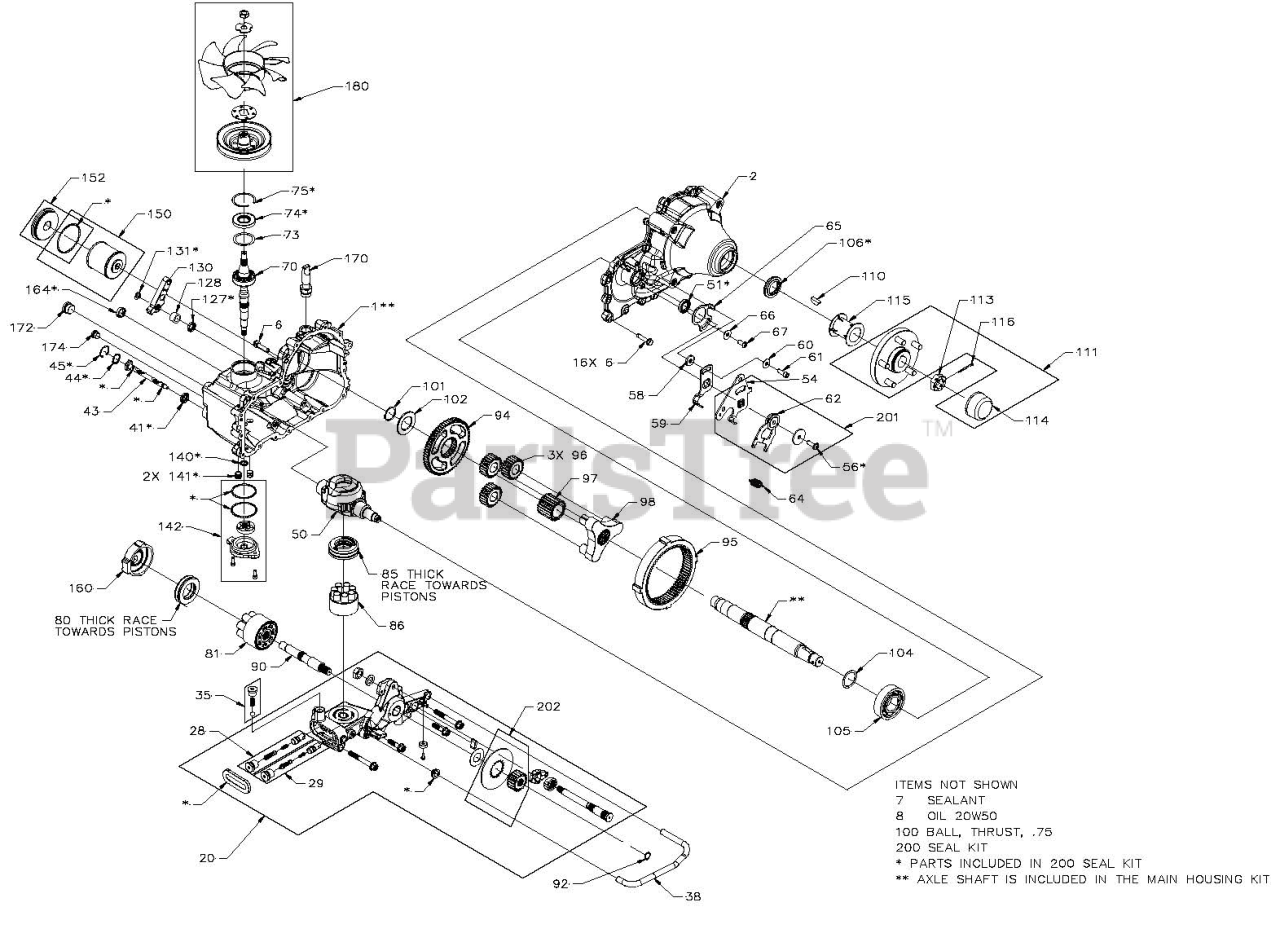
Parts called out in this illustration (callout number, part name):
1	KIT, HOUSING, MAIN, LH
2	KIT, HOUSING, SIDE, LH
7	SEALANT TUBE 10.1OZ.
8	KIT, HYDRO OIL ZT5400
20	CENTER SECTION L(03935300)
28	HG SHOCK VALVE KIT
29	HG SHOCK VALVE KIT
35	HG CHARGE RELIEF VALVE KIT
38	TUBE, FILTER, LH
41	SEAL, LIP 12 X 24 X 5 TC
43	ASSEMBLY, ACTUATOR BYPASS
44	SPRING, WAVE
50	SWASHPLATE, 16CC, MACHINED
54	ARM, CONTROL, LH
56	TWHCS 5/16-24 X 1.00
59	ARM, NEUTRAL LEFT
61	SHCS 5/16-24X1 PATCH
62	ARM, SCISSOR
64	RTN SPRING HG 51605
65	PLATE, STOP, LH
70	INPUT SHAFT HG 71941
74	SEAL, LIP 25 X 52 X 7 TC
75	RING, RETAINING, INTERNAL
80	BRG, THRUST (21) 42X68X16, PLASTIC CAGE
81	KIT, MOTOR BLOCK
86	KIT, BLOCK, 16CC CYLINDER
90	SHAFT, MOTOR
92	RING, RET 62 EXT
98	CARRIER
100	BALL, .75
102	SPACER, THRUST, AXLE
105	BEARING,BALL 35 X 80 X 21 6307
106	HG SEAL LIP 1.375X2.062X.250
110	KEY, WOODRUFF 5/16 X 1
111	HG 5 BOLT HUB KIT
113	HG HEX NUT 1-20 SLOTED
114	HG AXLE HUB CAP - ZT5400
116	PIN, COTTER 9/64 X 2 EXTENDED
130	BRAKE ARM HG 53018
131	CLIP,BRAKE ARM HYDROGEAR 52027
140	SEAL, .50 X .69 X .09 VC
141	TUBE, PUSH O-RING
142	CHARGE COVER KIT
150	FILTER,HYD OIL W/ORING ZT-54OO
152	HG FILTER PLUG KIT
160	PLATE, MOTOR, SWASH
164	SEAL, PLUG
170	FITTING, 7/8-14 SAE, .625 BEADED
172	PLUG, 7/8-14, METAL
174	PLUG, 9/16-18, METAL
180	PULLEY/FAN KIT HG 71906
200	SEAL KIT HG 71945
201	KIT, RTN, BIDIRECTIONAL
202	KIT, BRAKE ROTOR, GEAR
